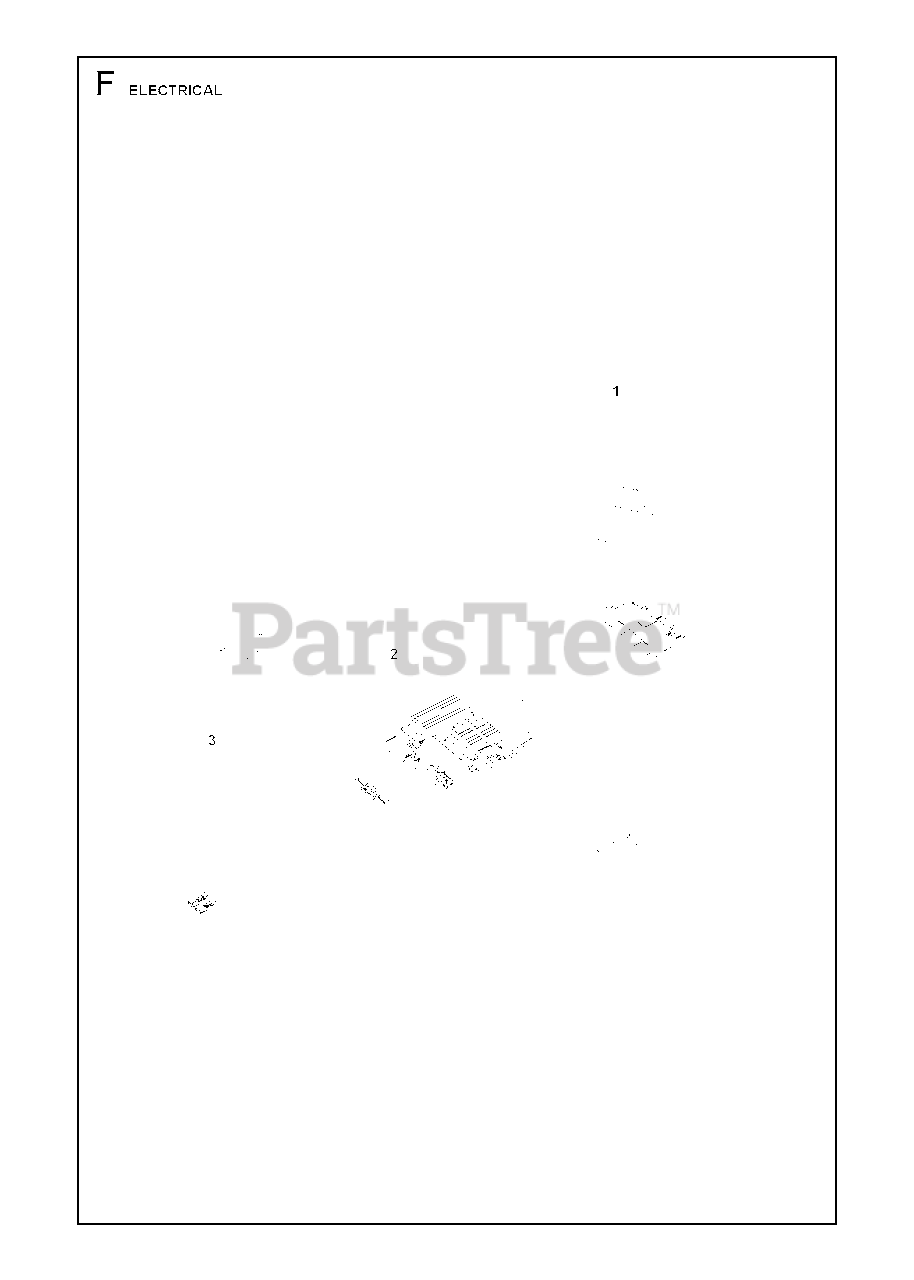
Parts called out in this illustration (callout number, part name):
1	MAIN SWITCH
2	CONTROL UNIT CONTROL
3	MICRO SWITCH
